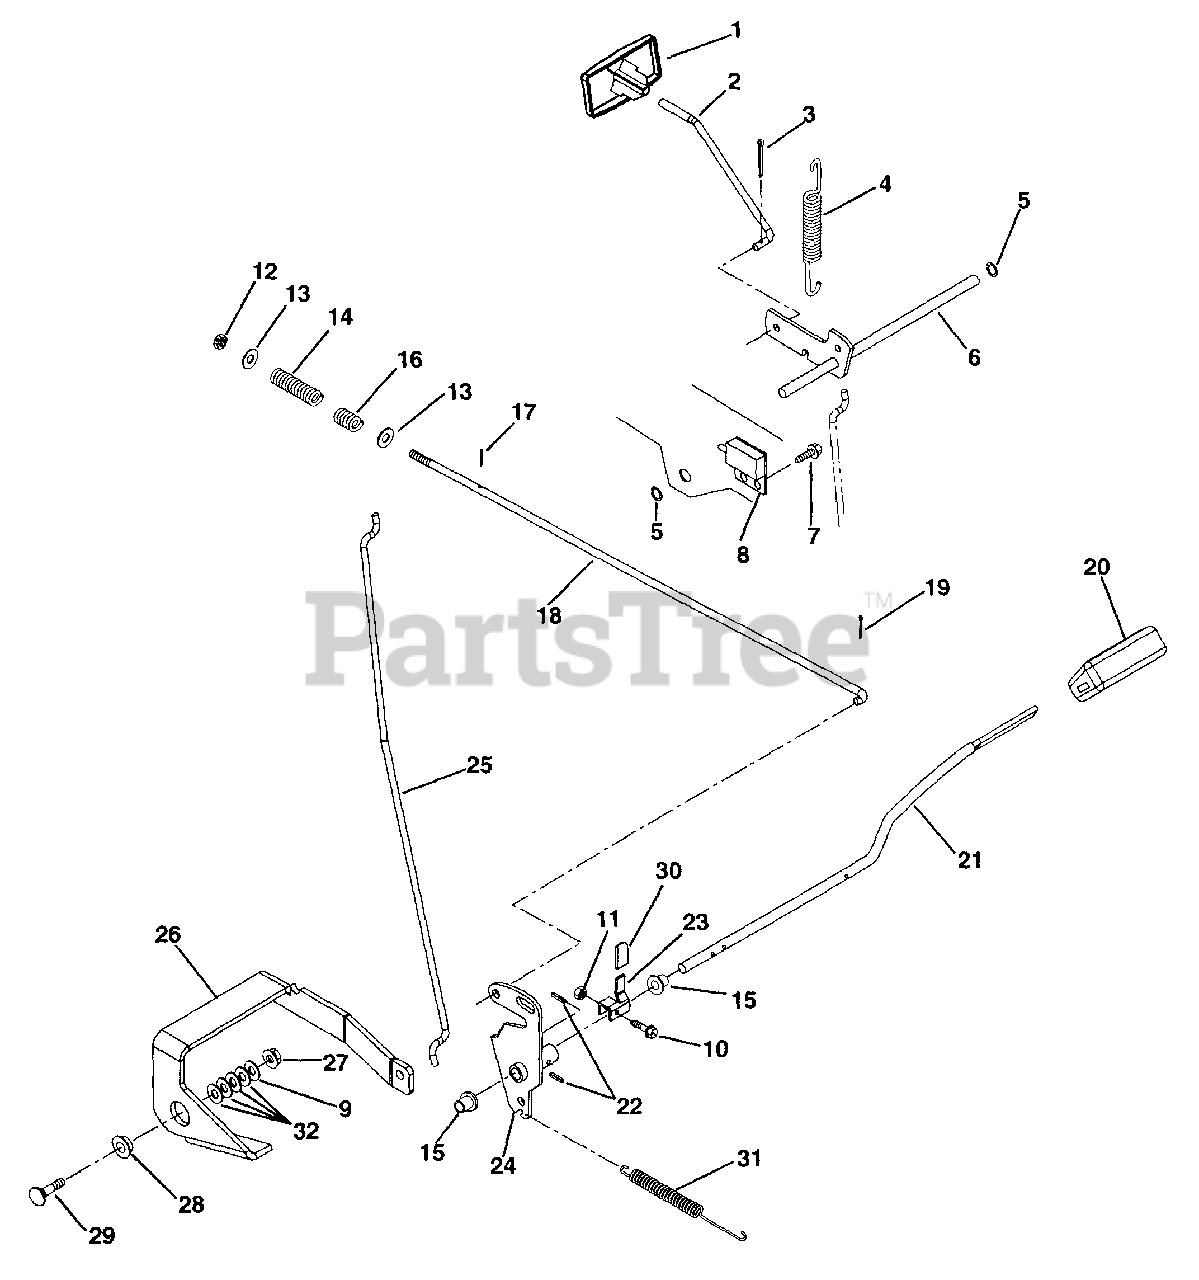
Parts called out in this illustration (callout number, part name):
1	Knob-Park Brake
3	Pin-Cotter .06 x .50
4	Spring-Tension .051 x .60 x 2.25
5	Ring-Retaining-External .250 x .010
6	Bellcrank-Parking Brake
7	Screw-Tapping 12-24 x .50 Hex Washer Head
8	Switch-Single Pole N.O.
9	Washer-Flat Steel .38 x .875 x .083
10	Screw 10-24 x 1.00
11	Nut-Nylon Lock 10-24
12	Nut-Locking-Center .38-16
13	Washer-Flat-Steel .406 x .812 x .065
14	Spring-Compression 2.00 x .437
15	Bushing-Flange .515 x .75 x .745 x 1.00
16	Spring-Compression .62 x .68 x 1.75
17	Pin-Roll .125 x .75
18	Rod-Brake
19	Pin-Cotter .09 x .75
20	Cover-Pedal-Brake
21	Pedal-Brake
22	Pin-Groove .188 x 1.25
23	Lever-Brake Switch
24	Arm & Hub-Brake
25	Rod-Parking Brake
26	Lever-Parking Brake
27	Nut-Locking-Flange .312-18
28	Shoulder Spacer
29	Bolt-Round Head Square Neck .31-18 x 1.0
30	Grip .062 x .375 x .750
31	Spring-Tension .095 x .85 x 4.38
32	Washer-Plastic .390 x .875 x .062
